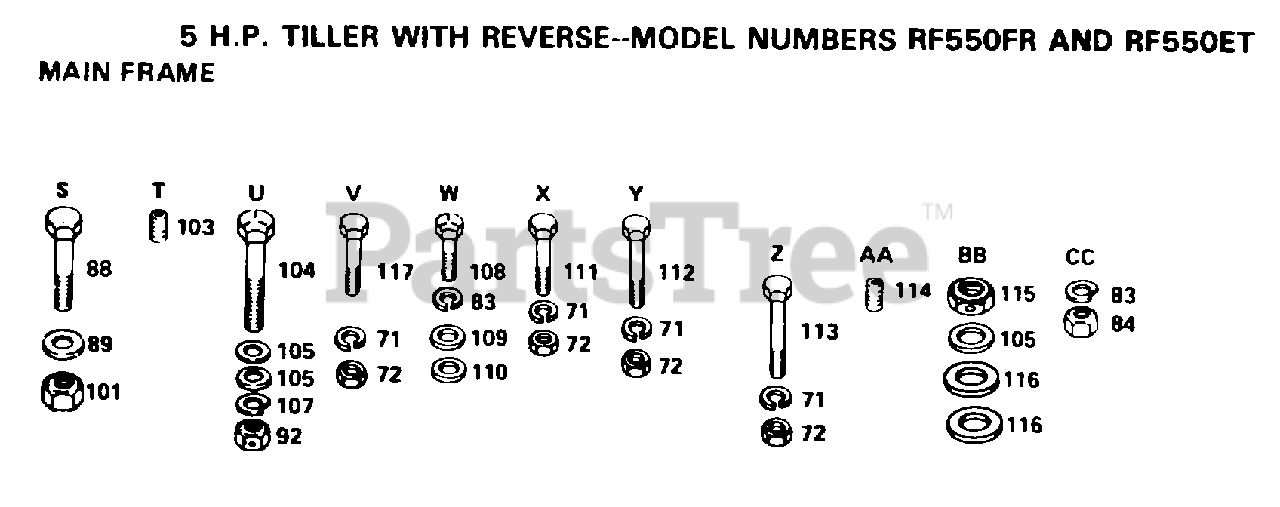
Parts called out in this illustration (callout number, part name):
71	LOCKWASHER
72	NUT.HEX.5/16-18
83	LOCKWASHER
89	WASHER
92	GRIPCO NUT
101	NUT.HEX.3/8-16UNC
103	SET SCREW
105	WASHER
107	LOCKWASHER
108	BOLT
109	WASHER
110	WASHER
111	BOLT
114	SET SCREW
117	BOLT.HEX.5/16-1.5
